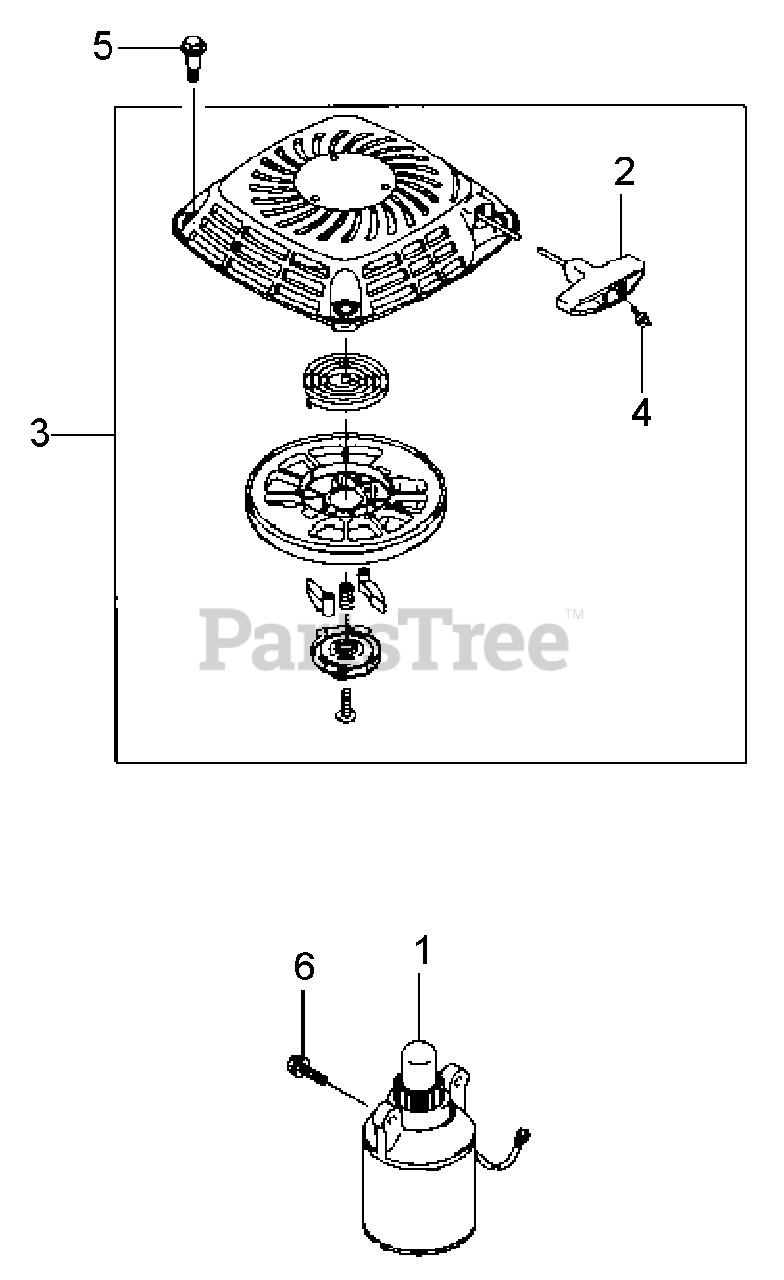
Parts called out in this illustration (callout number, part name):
1	Electric Starter
3	Recoil Starter
5	Bolt, M6
6	Flanged Bolt
